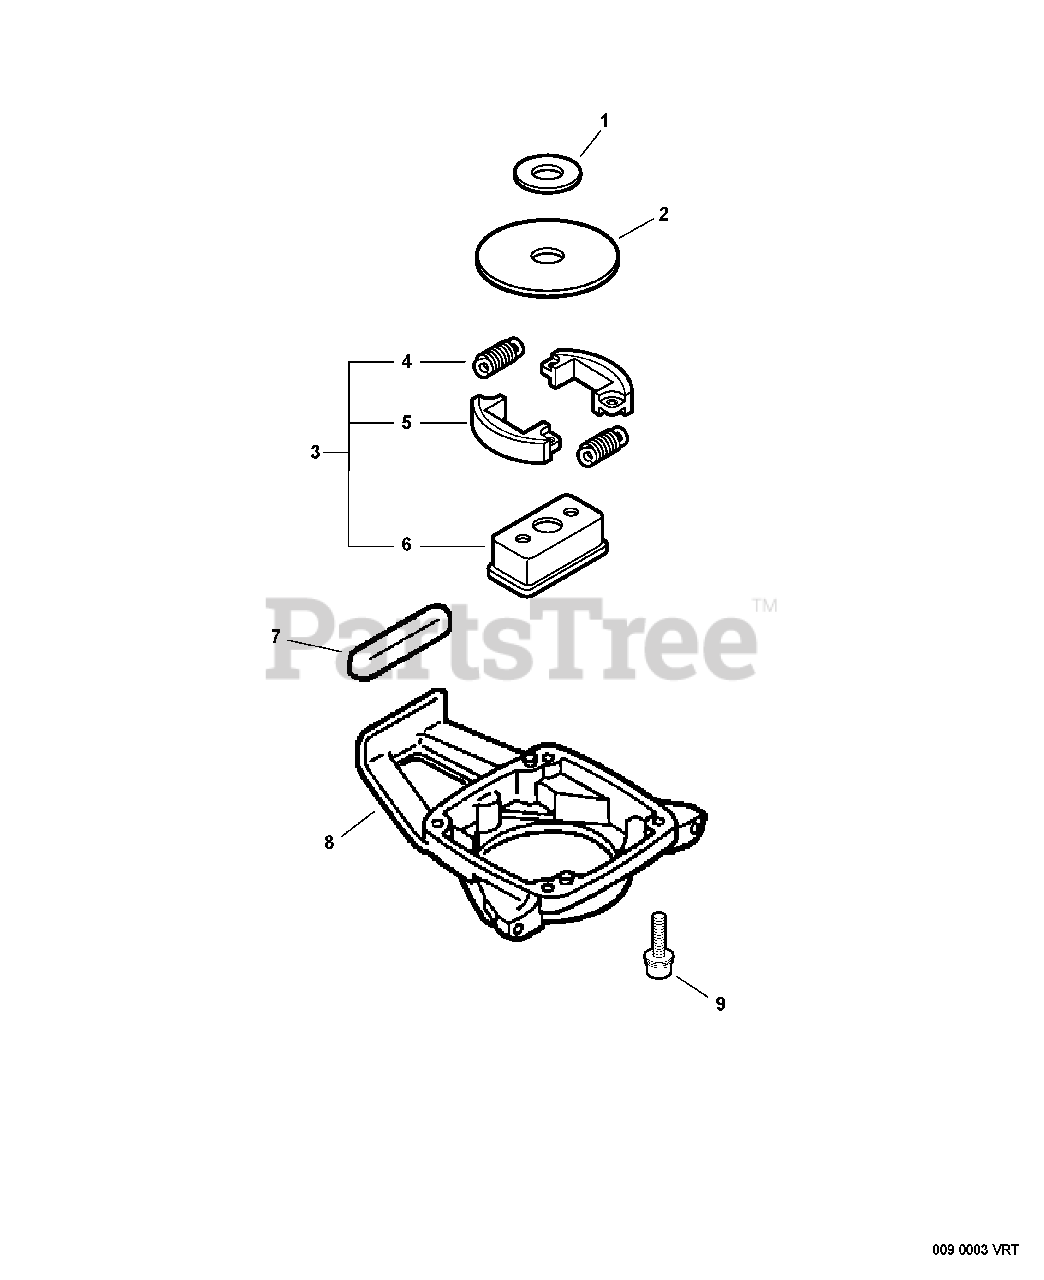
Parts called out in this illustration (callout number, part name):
1	WASHER, CLUTCH
2	PLATE, CLUTCH
3	CLUTCH ASSY
4	SPRING, CLUTCH
5	SHOE, CLUTCH
6	HUB, CLUTCH
7	CUSHION, FUEL TANK
8	HOUSING, CLUTCH
9	BOLT 4×16
